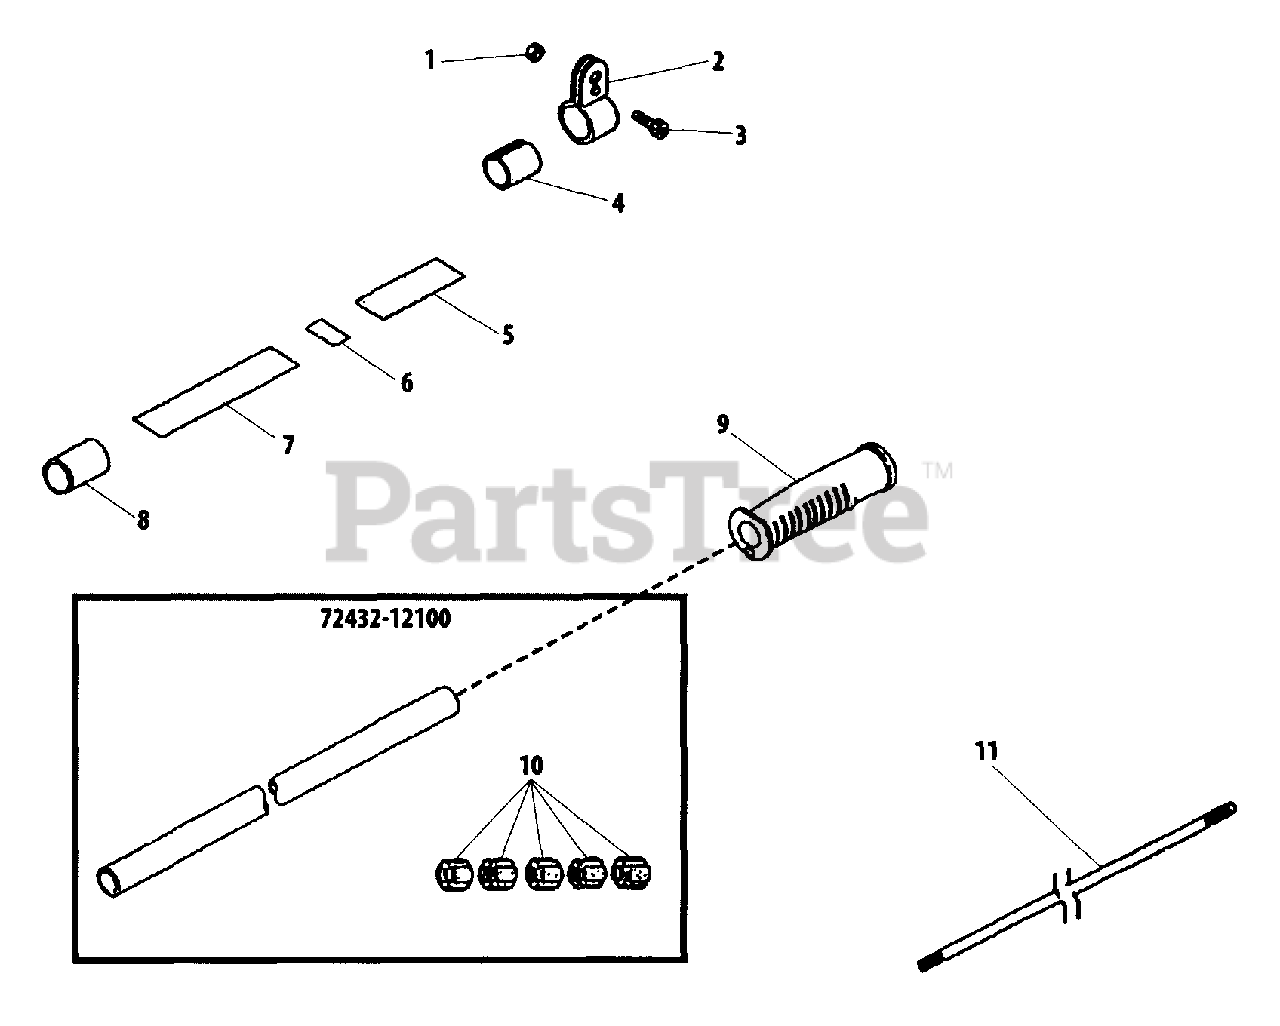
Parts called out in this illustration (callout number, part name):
2	BRACKET
3	SCREW - 5X12
4	SPACER
5	LABEL - CAUTION
6	LABEL - ALIGNMENT
7	LABEL
8	CAP, MAIN PIPE
9	GRIP - REAR
10	BUSHING
11	PIPE, MAIN
72432-12100	MAIN PIPE ASSY
